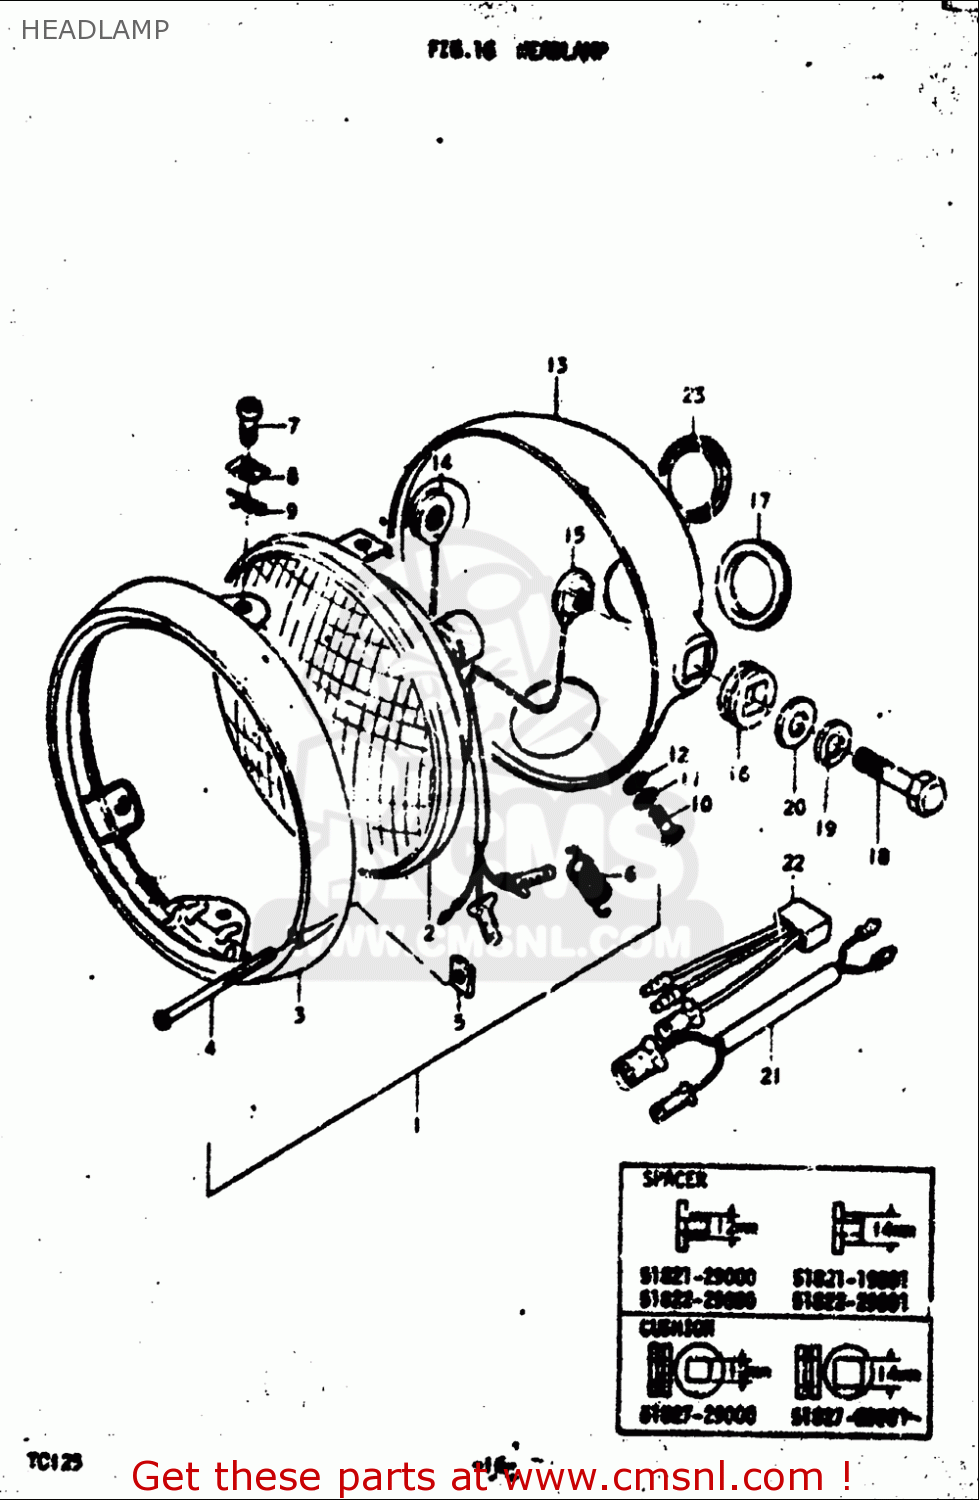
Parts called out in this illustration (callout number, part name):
4	SCREW,HEADLAMP ADJUST
5	NUT,HEADLAMP ADJUSTER
7	SCREW,LENS
8	NUT
10	SCREW
11	WASHER,LOCK
12	WASHER
13	HOUSING,HEADLAMP
16	CUSHION,HEADLAMP HOUSING
18	BOLT
19	WASHER,LOCK
20	WASHER
23	CAP
